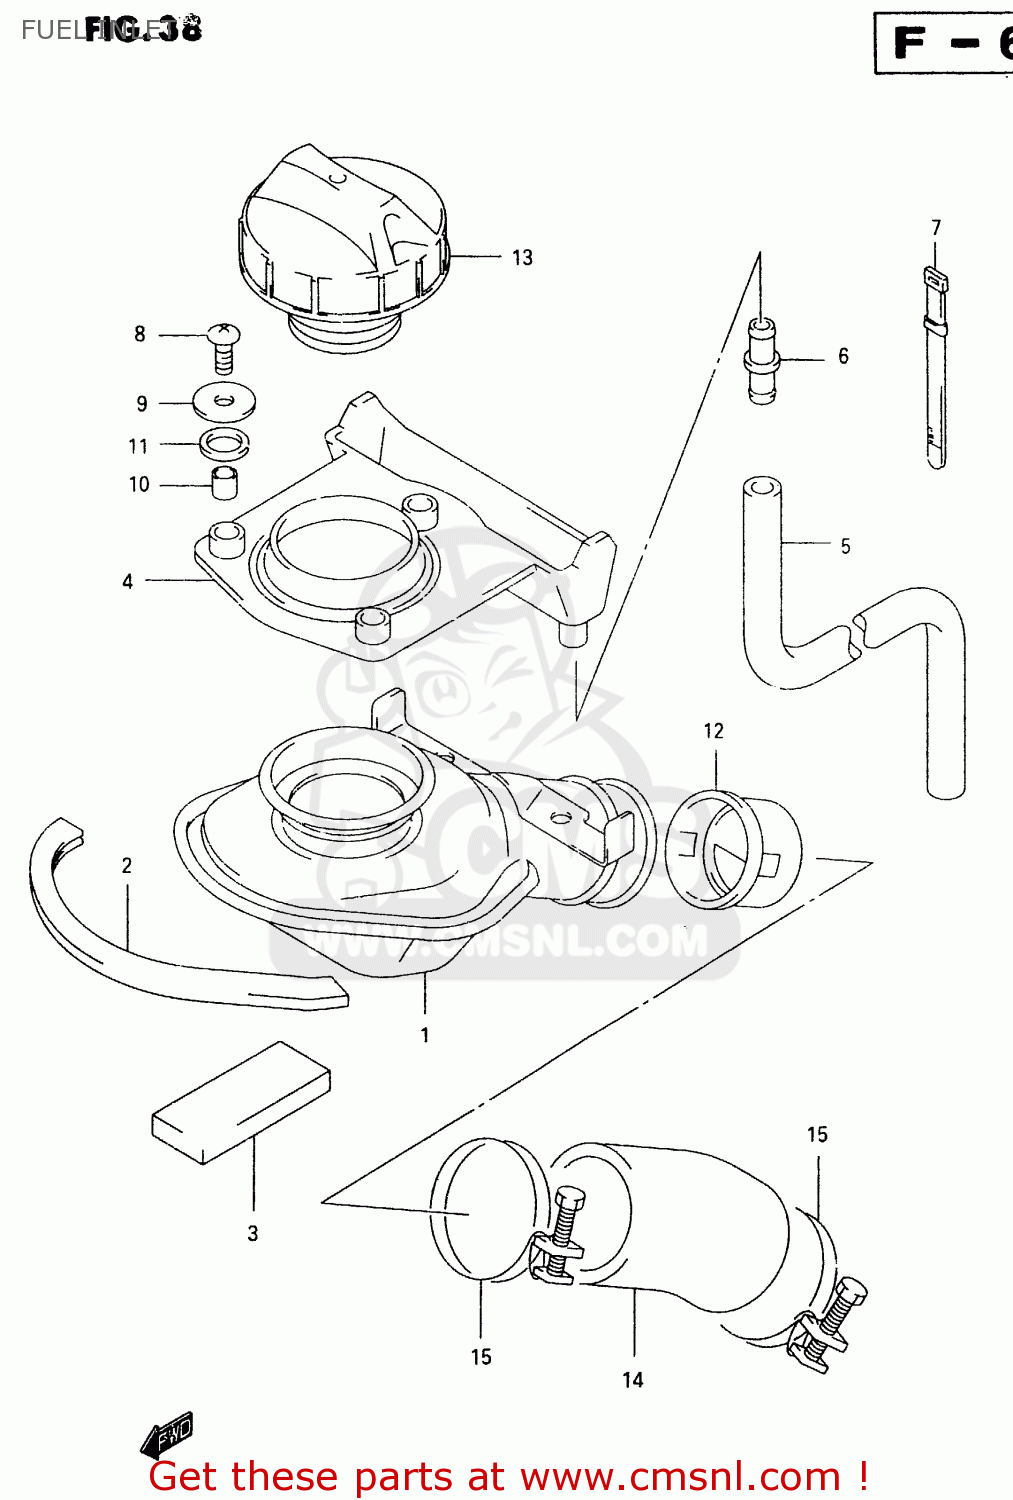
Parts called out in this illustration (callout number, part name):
1	INLET,FUEL TANK
2	MOLDING
3	CUSHION
4	TRAY,FUEL TANK INLET
5	HOSE(7X10.2X2000)
6	JOINT
7	CLAMP(L:165)
8	SCREW
9	WASHER(5.5X20X1.4)
10	SPACER(5.5X8X7.5)
11	CUSHION,FUEL TANK INLET UPR
12	VALVE,FUEL TANK INLET
13	CAP ASSEMBLY,FUEL TANK FILLER
14	HOSE,FUEL TANK FILLER
15	CLAMP
